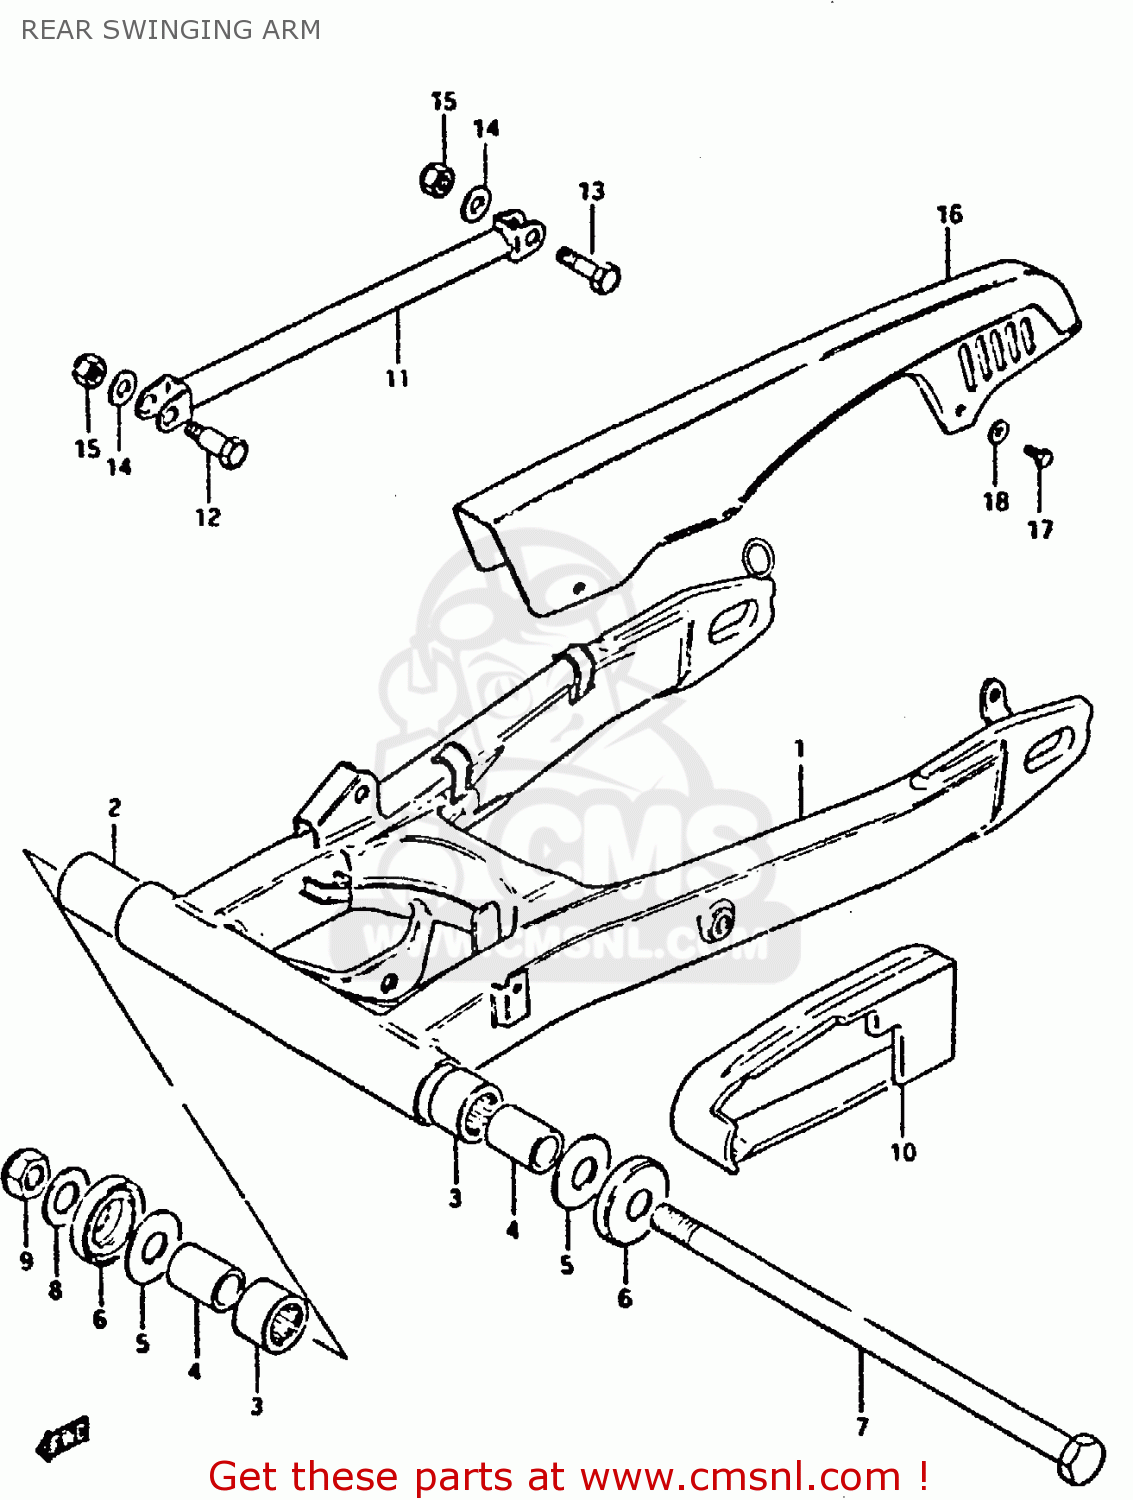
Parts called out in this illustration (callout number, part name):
1	ARM,REAR SWING
2	SPACER,SWING ARM,CENTER
3	BEARING(25X33X30)
4	SPACER,RR SWGARM PIVOT
5	WASHER
6	COVER,RR SWGARM DUST SEAL
7	SHAFT,REAR SWING ARM
8	WASHER
9	NUT
10	BUFFER,CHAIN TOUCH DEFLECTOR
11	LINK,REAR TORQUE
12	BOLT
13	BOLT(10X39)
14	WASHER
15	NUT
16	CASE,CHAIN
17	BOLT
18	WASHER
